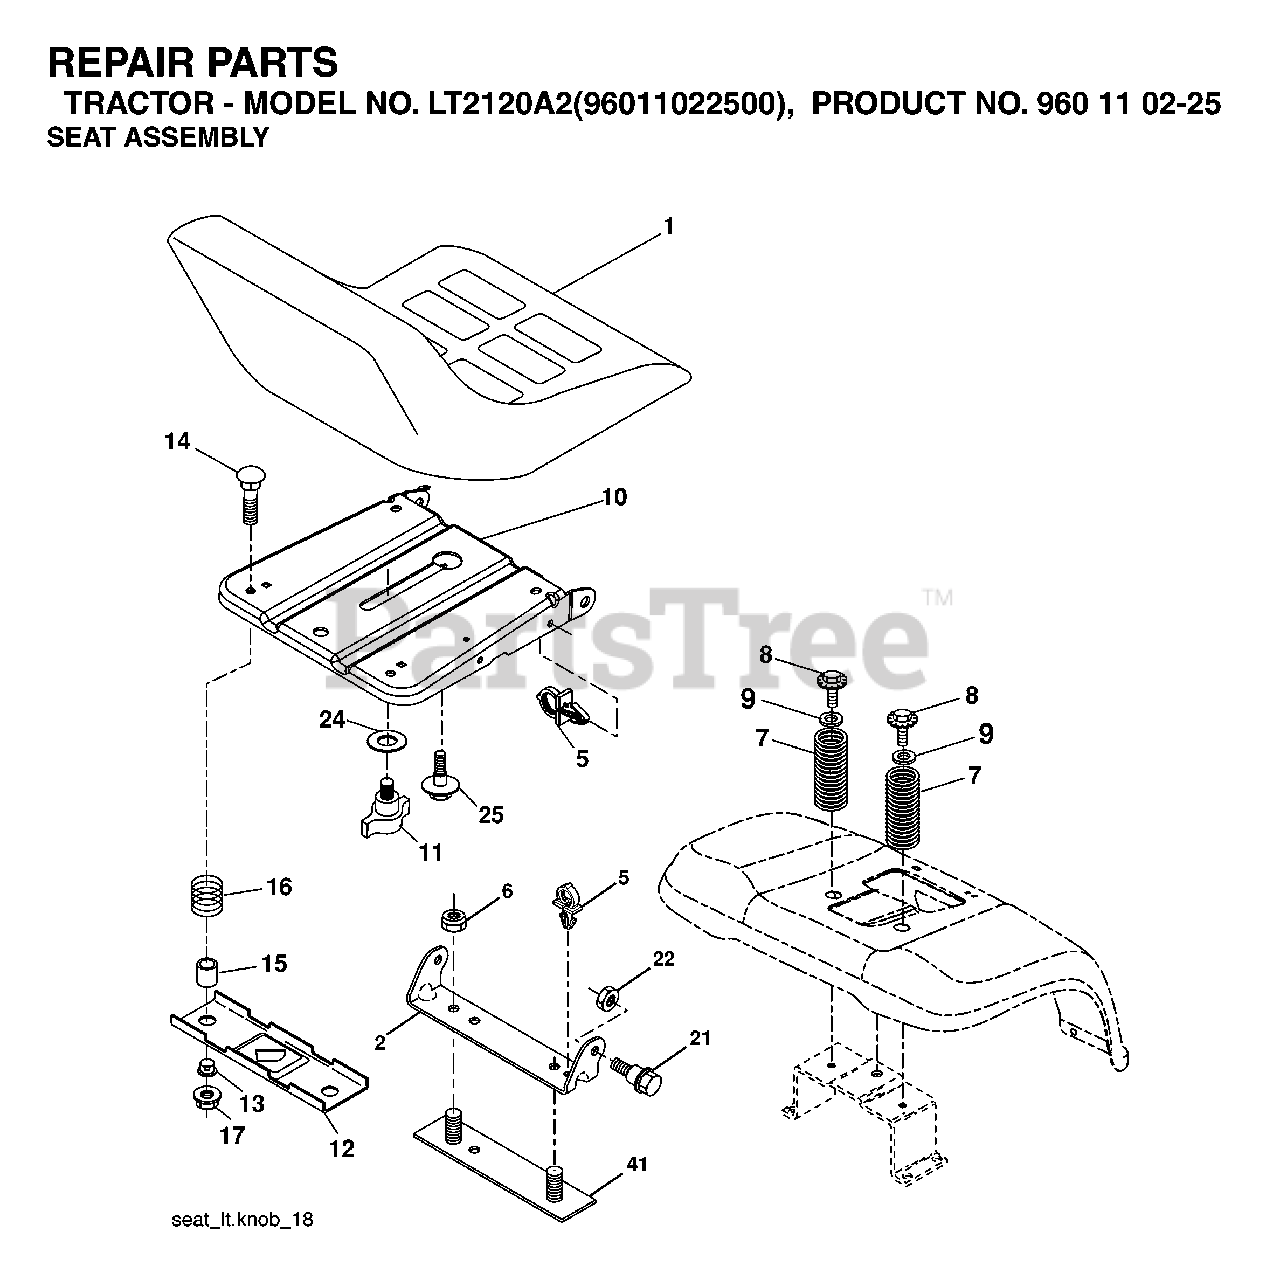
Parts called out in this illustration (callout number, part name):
1	SEAT.XG150.BLK.KB/SLD.NO-LOGO
2	SEAT PIVOT BRKT
5	PUSH CLIP
6	NUT
7	SPRING COMPRESSION
8	SCREW 3/8-16X1
9	WASHER
10	PAN.ASM.SEAT.1SLOT
11	KNOB.SEAT.ADJ.WINGNUT
12	BRKT SWITCH
14	BOLT.ROUND.HEAD.SQUARE.NECK
15	SPACER SPLIT
16	SPRING COMPRESSED
17	NUT T
21	BOLT.SHOULDER.5/16-18
22	NUT.71038.31-18.HEX.NYLOCK
25	BOLT,SHOULD
